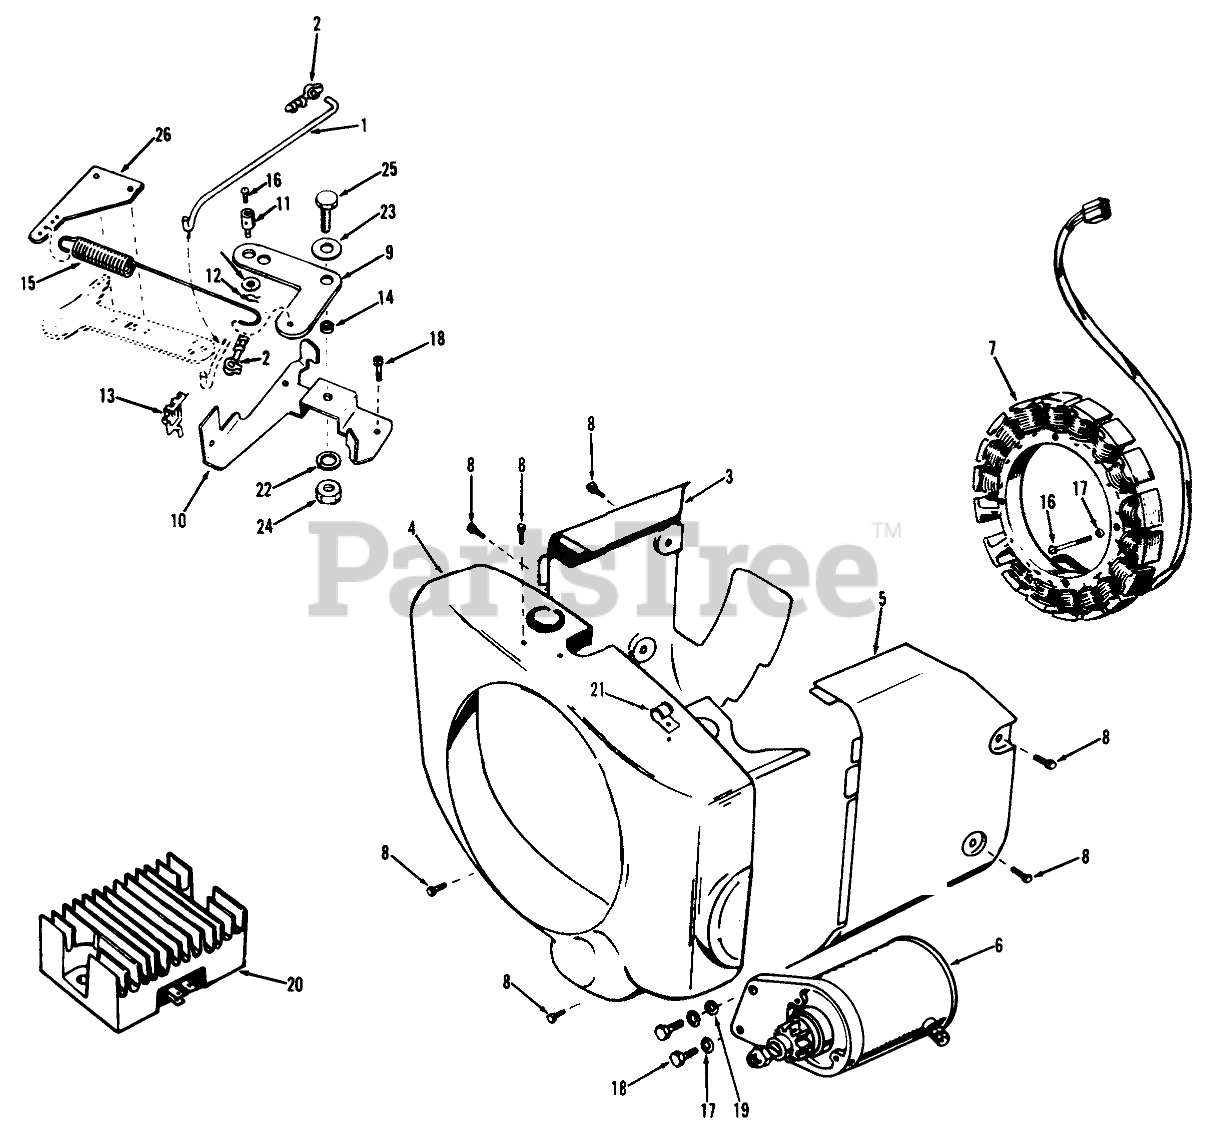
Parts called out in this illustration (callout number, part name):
1	ROD-GOV CONTROL
2	GOV END-CONTROL ROD
2	Carburetor End
3	Shroud-Left Side
4	Blower Housing
5	Shroud-Right Side
7	Alternator Stator
8	Bolt 1/4-20 X 7/16
9	Governor Control Arm
10	Governor Mounting Bracket
14	Governor Control Bushing
15	Governor Spring
16	Round HD Screw 10-32 X 1 1/2
17	Lockwasher 5/16 Starter
17	Stator Mounting (#10)
18	Hex Bolt #8 X 3/8 Governor
18	Hex Bolt 5/16-18 Starter
19	Washer-Starter-Top Hole
21	Clip-Fuel Hose
22	Lockwasher 1/4
23	Washer
24	Nut 1/4-20
25	Hex Bolt
26	ADAPTOR-GOV ARM
